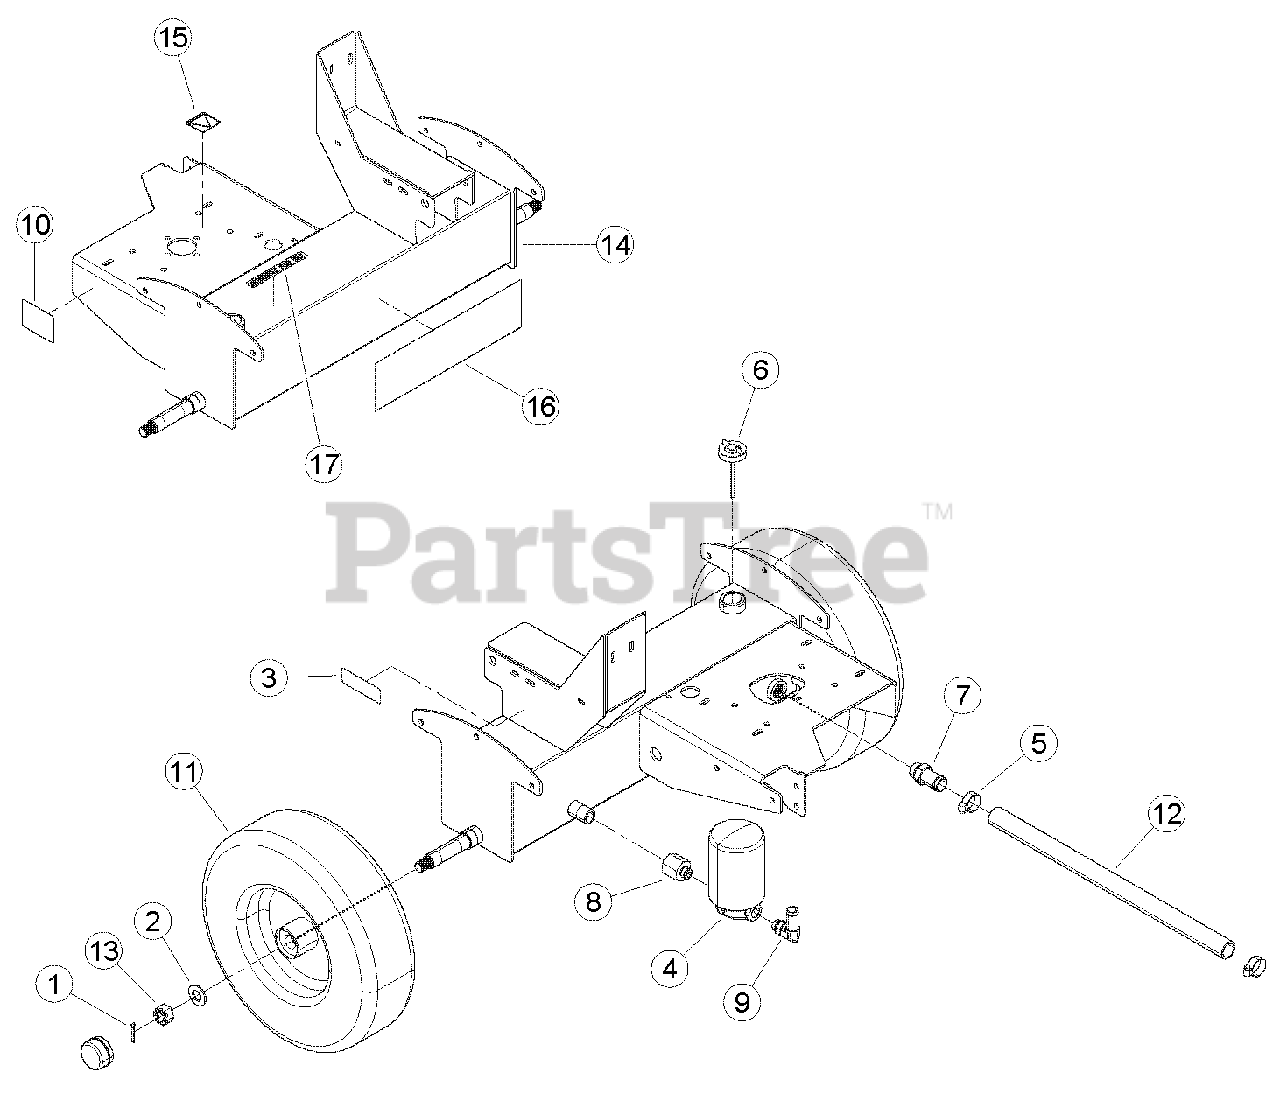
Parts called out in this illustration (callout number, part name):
1	PIN, 5/32 X 1-1/4 COTTER ZP
2	WASHER, 3/4 SAE FLAT ZP
3	DECAL, SERIAL NUMBER
4	FILTER, SPIN-ON
5	CLAMP, 1-1/4" HOSE
6	CAP, W/DIPSTICK
7	ADAPTER, 1" HOSE BEAD X -12 MORING
8	ADAPTER, -8 MORING / -12 FMNPT
9	ADAPTER, -8 MORING / 3/4" HOSE BARB 90
10	DECAL, 4.80-8 LOAD RATING
11	ASSEMBLY, TIRE 4.8-8
12	HOSE, 1.00 ID X 22 IN 100R4 HYD
13	NUT, SLOTTED 3/4-16 GRADE 2
14	WELDMENT, LOG SPLITTER TANK, SERVICE PART
15	DECAL, SHIELD DANGER ISO
16	DECAL, ECHO BEARCAT 14.12 X 4.00
17	DECAL, HYDRAULIC FLUID
